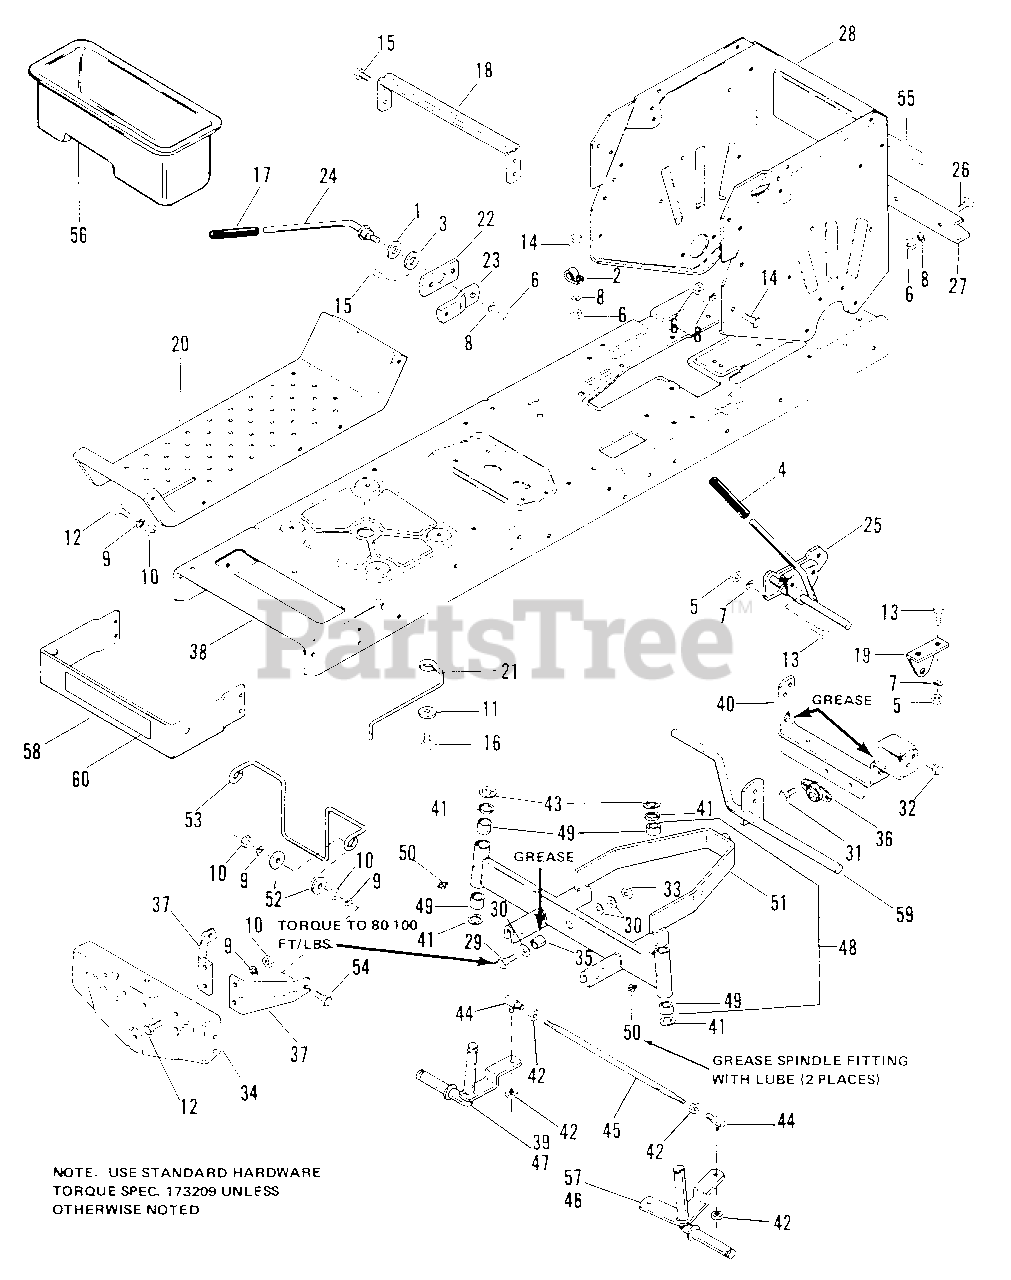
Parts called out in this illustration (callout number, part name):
1	WASHER, Steel
3	WASHER, Nylon
4	HANDLE, Grip
5	NUT, Hex, 1/4-20
6	NUT, Hex, 3/8-16
7	LOCKWASHER, Spring, 1/4
8	LOCKWASHER, Spring, 3/8
9	LOCKWASHER, Spring, 5/16
10	NUT, Hex, 5/16-18
11	WASHER, Plain, 5/16
12	CAPSCREW, Hex Hd., 5/16-18 x 3/4
13	CAPSCREW, Hex Hd., 1/4-20 x 5/8
14	CAPSCREW, Hex Hd., 3/8-16 x 3/4
15	SCREW, Tapping, 5/16-18 x 1/2
16	SCREW, Tapping, 5/61-18 x 7/8
17	GRIP
18	BRACE, Seat
19	SUPPORT, Clutch
21	STOP, Belt
22	BAR, Support
23	ARM, Lift
24	HANDLE, Lift
25	LEVER ASSY., Clutch
26	CAPSCREW, Hex Hd., 3/8-16 x 1
27	BAR, Draw
28	SUPPORT, Axle
29	CAPSCREW, Hex Hd., 1/2-13 x 1-1/2
30	WASHER, Plain, 9-16
31	SCREW, Washer Hd., 3/8-16 x 1/2
32	SCREW, Hex Washer Hd., 5/16-18 x 5/8
33	LOCKNUT, 1/2-13
34	FRONT AXLE SUPPORT
36	BEARING ASSY., Side Range
37	BRACE, Front Axle
39	SPINDLE ASSY., R.H. (6008 Only)
40	SUPPORT ASSY., Axle
42	NUT, Hex Jam, 3/8-24
43	RING, Retaining
44	BALL JOINT ASSY
46	SPINDLE ASSY., L.H. (6011 Only)
47	SPINDLE ASSY., R.H. (6011 Only)
48	AXLE ASSY., Front (Includes Ref. No. 49 & 50)
50	FITTING, Lube
52	WASHER, Plain, 1/4
53	STOP, Belt
54	CAPSCREW, Hex Hd., 5/16-18 x 1-1/2
55	DECAL, Transaxle
56	TOOL TRAY
57	SPINDLE ASSY., L.H. (6008 Only)
59	LEVER ASSY., Brake
60	DECAL, Simplicity
